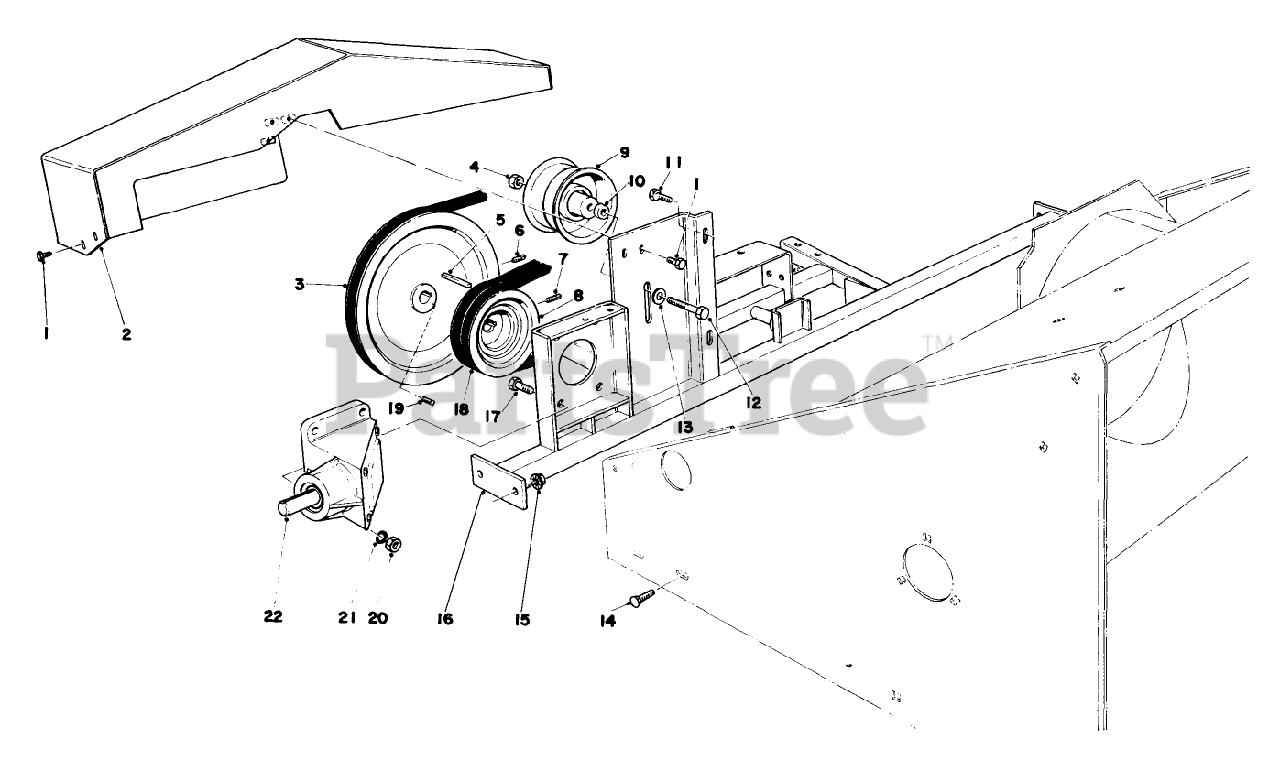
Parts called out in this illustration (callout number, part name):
1	SCREW-HHF
2	BELT SHIELD WA
3	SHEAVE 60014
4	NUT-LOCK, CONE
6	SCREW-SQH
7	SCREW-SET, SQH
8	PULLEY
9	Idler Pulley
10	IDLER SPACER
11	SCREW-HH
12	SCREW-HH
13	WASHER-FLAT
14	SCREW-CARR
15	NUT-HHF, WHIZ
16	Cross Brace
17	SCREW-HH
18	V-BELT
19	SCREW-SET, SQH
20	NUT-HEX
21	WASHER-LOCK
22	Gear Box Assembly
